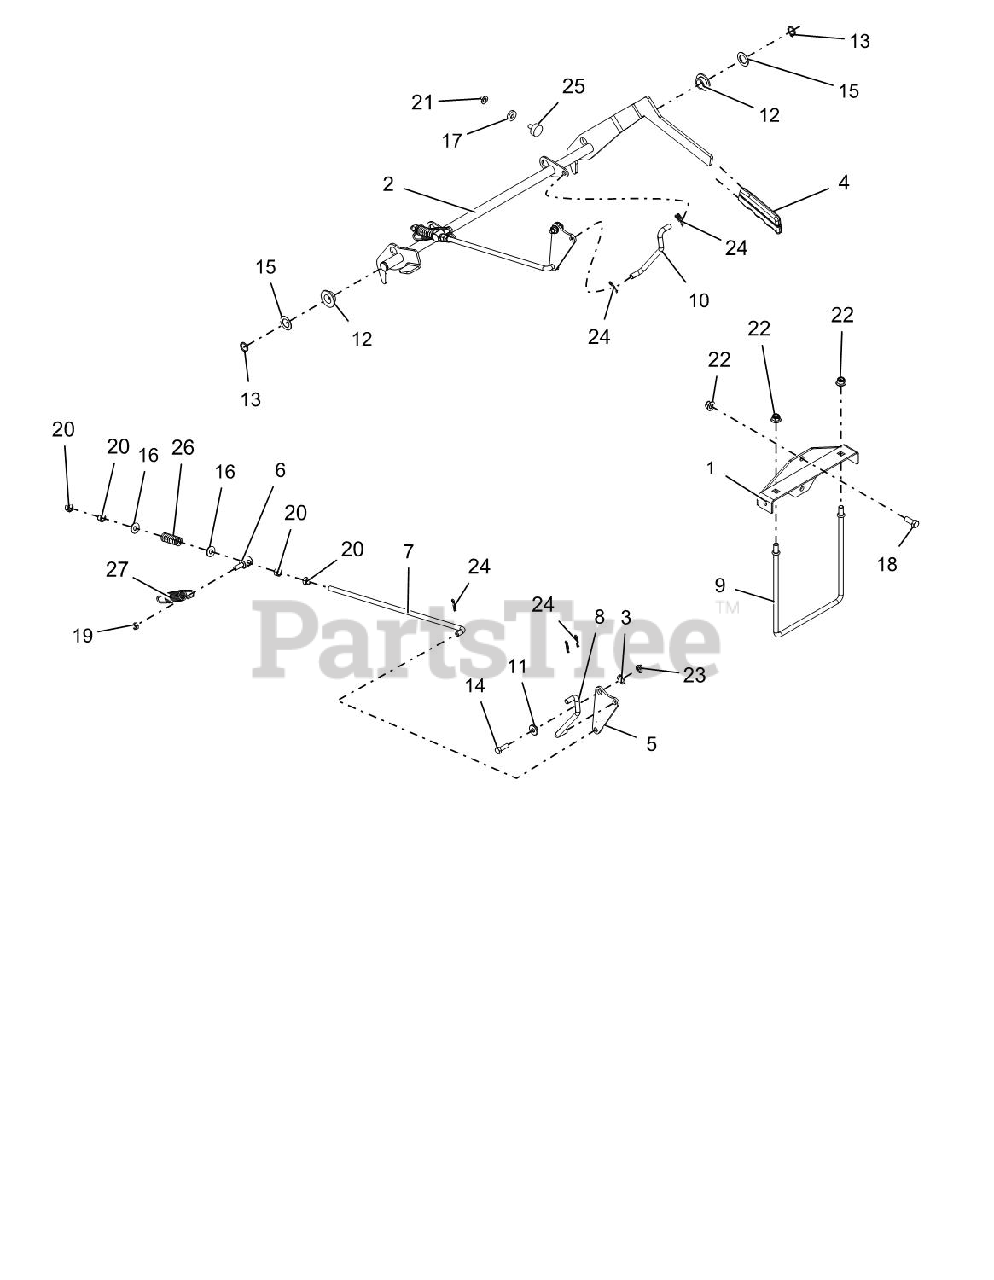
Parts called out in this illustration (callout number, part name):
1	SPRING ANCHOR BRKT WMT - BLACK
2	WLDMT,PT200/400 PARK BRAKE-GAS
3	WAVE WASHER .531X.781X.125FH
4	GRIP, PARKING BRAKE (YELLOW)
5	PLATE, BRAKE PIVOT
6	TRUNNION, .38-16
7	ROD, BRAKE ADJ.
8	LINKAGE, RH BRAKE ACTUATING
9	ROD, BRAKE MTG
10	LINKAGE, LH BRAKE ACTUATING
11	BSHG-FLG .32X.500X.344X.880
12	BSHG-FLG .762X1.48X.44 NYL
13	RG-RTNG-EXT .689X.078
14	BLT-HEX .31-18X1.00 GR5 YWZC
15	WSHR-HDND-THRST .758X1.23X.031
16	WSHR-FL-STL.38X.875X.083 YWZC
17	WSHR-FL-STL .328X.87X.179 YWZC
18	BLT-HEX .38-16X1.00 GR5 YWZC
19	NUT-LK-CTR-JAM .31-18 YWZC
20	NUT-HEX .38-16 YWZC
21	NUT-SPNLK-FLG .312-18 YWZC
22	NUT-LK-NYL-FLG .38-16 YWZC
23	NUT-LK-TOP-FLG .31-18 YWZC
24	PIN-HAIR, ENDRIES #25 YWZC
25	BUMPER, RUBBER
26	SG-COMP .142 X .710 X 1.75
27	SPRING-TENS .105X.850X.4.880
